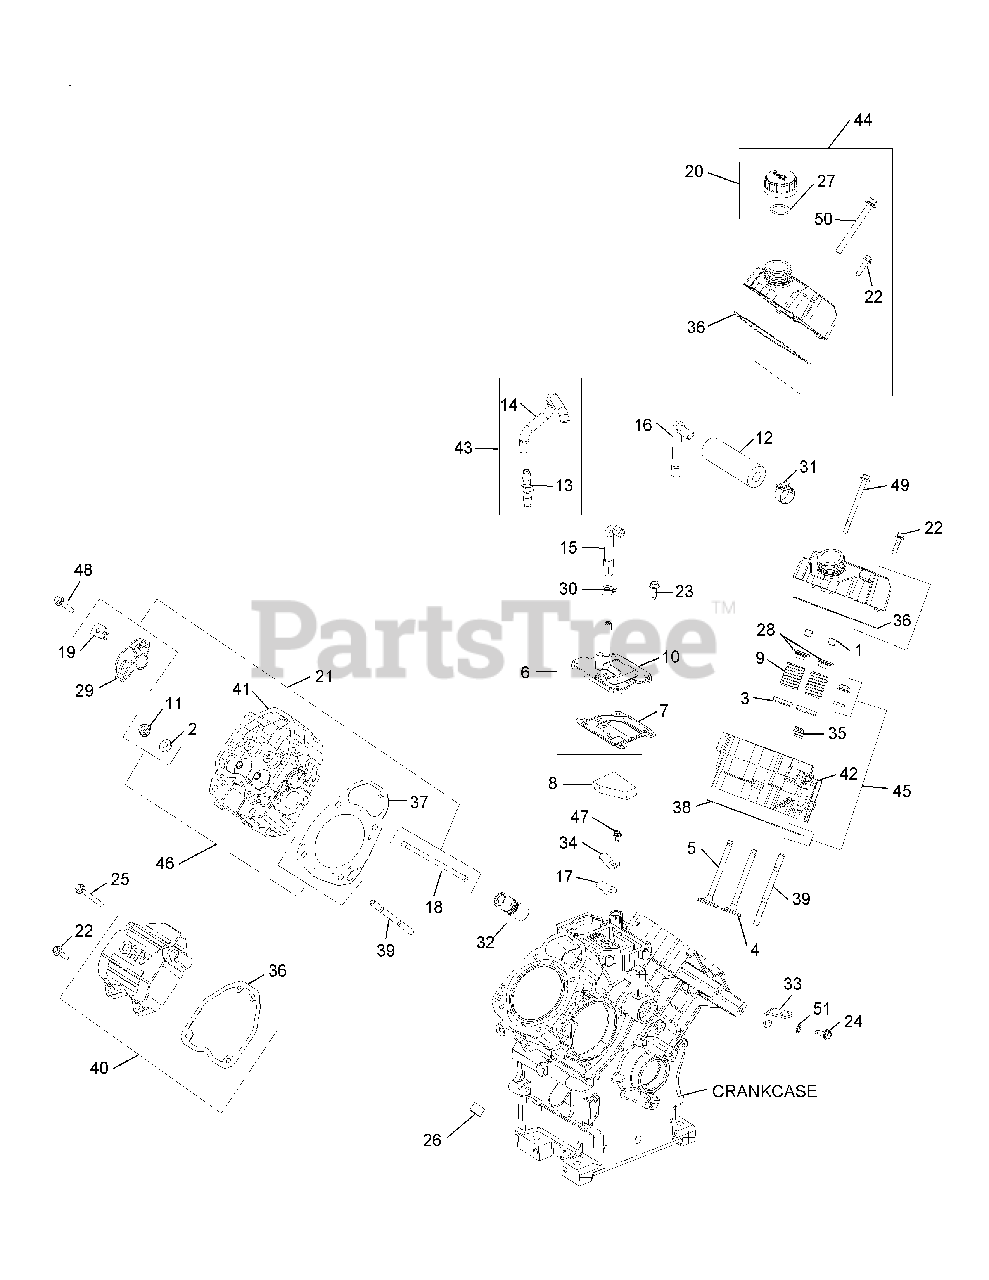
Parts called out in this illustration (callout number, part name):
1	Retainer Kit
2	Washer, Flat 5/16"
3	Retainer, Spring
4	Valve, Exhaust (Std)
4	Valve, Exhaust (.25)
5	Valve, Intake (Std)
5	Valve, Intake (.25)
6	Kit, Breather Assy
7	Gasket, Breather
8	Filter, Breather
9	Spring, Valve
10	Kit, Breather Assy
11	Nut, Flg M8x1.25
13	Fitting, Breather
14	Hose, Breather
17	Reed, Breather
19	Pivot, Rocker Arm
20	Kit, Oil Fill Cap (Yellow)
21	Kit, Valve Train
22	Screw, Flg M6x1.0x25
23	Screw, Thread Forming
26	Plug, Pipe Ctsk 3/8"
27	O-Ring, Dipstick
28	Cap, Valve Spring
30	Clamp, Band Spring Hose
32	Hydraulic Valve Lifter
33	Strap, Lifting
34	Retainer, Reed
35	Seal, Valve Stem
36	Gasket, Valve Cover
37	Kit, Cyl Head Gasket (#1 Side)
38	Kit, Cyl Head Gasket (#2 Side)
40	Kit, Rocker Cover
41	Kit, Cyl Head (#1 Side)
42	Kit, Cyl Head (#2 Side)
43	Hose Assy, Breather
44	Kit, Lh Oil Fill Valve Cover
45	Kit, Cyl Head Gasket (#2 Side)
46	Kit, Cyl Head Gasket (#2 Side)
47	Screw, Flg Thd Frm M5x.8X10
48	Screw, Flg M6x1.0x34
